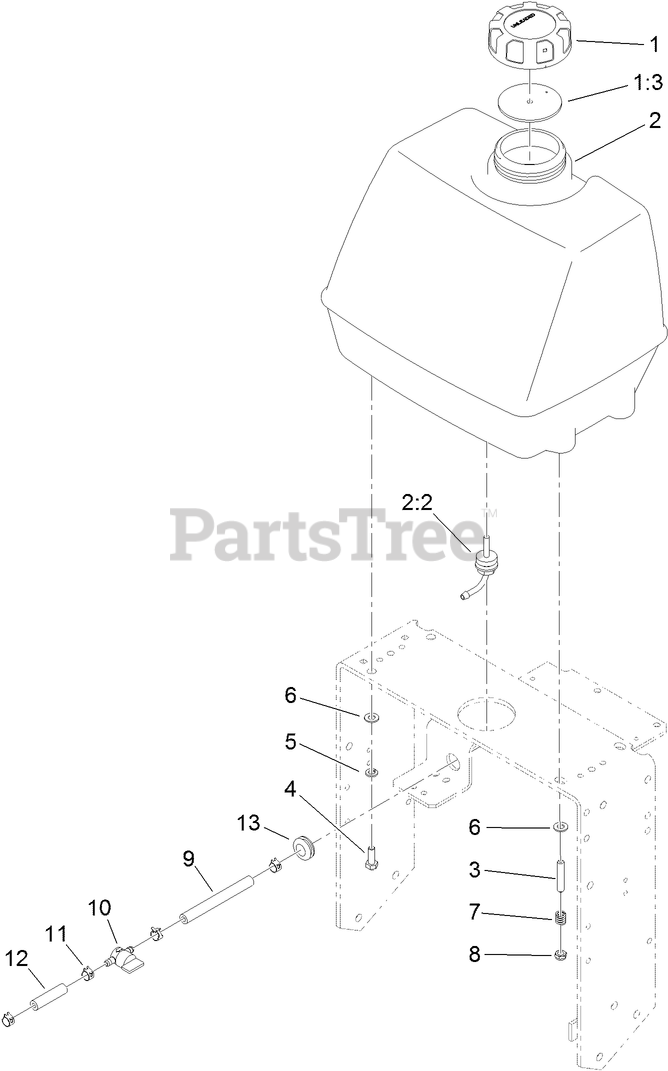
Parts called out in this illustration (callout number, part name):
1	GAS CAP ASM
1:3	GASKET-CAP, GAS
2	FUEL TANK ASM
2:2	FITTING-FUEL, BULKHEAD
3	STUD-THREADED
4	SCREW-HH
5	WASHER-LOCK
6	WASHER-PLAIN
7	SPRING-TANK, FUEL
8	NUT-LOCK, NI
9	HOSE-FUEL
10	VALVE-FUEL
11	CLAMP-HOSE
12	HOSE-FUEL
13	GROMMET
